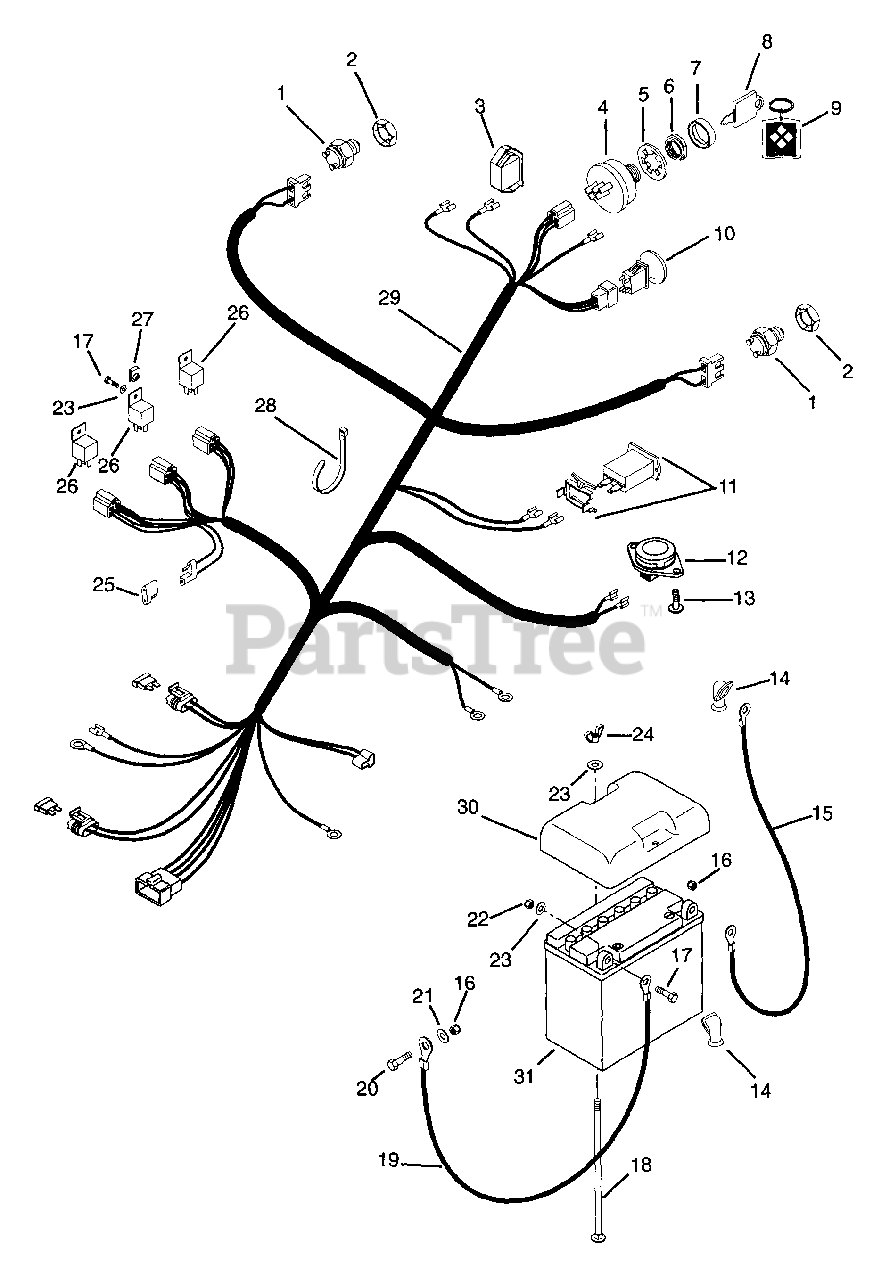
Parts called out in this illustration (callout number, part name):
1	Switch-Neutral Start N.O.
2	Nut-Stamped .56-18
3	Light-Indicator
4	Key Switch
5	Washer-Locking-Internal .625 x .045
6	Nut-Panel .562-24
7	Cap-Ignition Switch
8	Ignition Switch Key
9	Key Chain
10	Switch-Clutch w/Retainer Ring
11	Hour Meter
12	Switch-Seat
13	Bolt-Hex .25-20 x .50 Grade 5
14	Insulator
15	Start Cable 22"
16	Nut-Locking-Nylon .31-18
17	Bolt-Hex .25-20 x .75 Grade 5
18	Bolt-Round Head Square Neck .25-20 x 7.00 Grade 2
19	Cable-Negative Battery
20	Bolt-Hex .312-18 x .750 Grade 5
21	Washer-Flat-Steel .312 x .734 x .065
22	Nut-Locking-Center .250-20
23	Washer-Flat-Steel .281 x .620 x .065
24	Nut-Locking-Wing .250-20
25	Molded Diode Plug
26	Relay
27	Nut-Retainer .25-20 x .56
28	Tie Wrap-Black
29	Harness-Wiring 18HP Kohler
30	Cover-Battery
